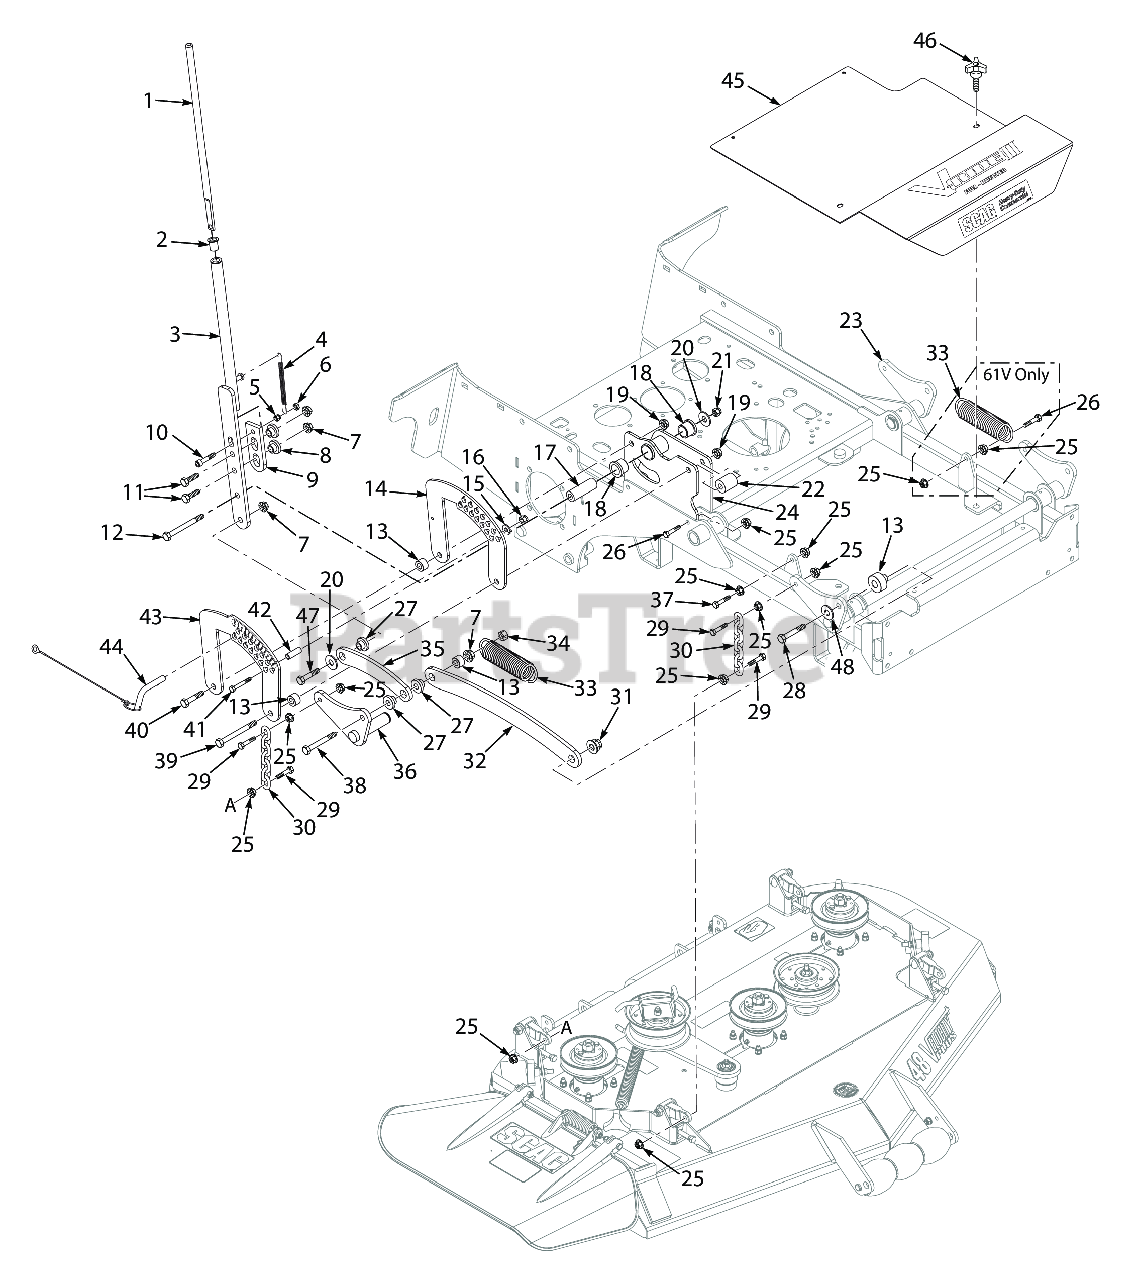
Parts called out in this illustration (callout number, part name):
1	Actuator Rod, Deck Latch
2	Bearing, .625 ID Plastic
3	Handle Weldment, Deck Latch
4	Spring, Deck Latch
5	HEX NUT, ELASTIC STOP LOCK, 3/8-16
6	Bolt, Hex Head 3/8-16 x 1" Ser. Flg.
7	Nut, Hex Serrated Flange 1/2-13
8	Bushing, Deck Latch
9	Deck Latch, Outer
10	Capscrew, Socket Head 3/8-16 x 1-3/4"
11	Bolt, Hex Head 1/2-13 x 1-3/4"
12	Bolt, Hex Head 1/2-13 x 4-1/4"
13	Bushing. Deck Latch
14	Bracket, Deck Height
15	Flatwasher, 3/8" Special (.391 x .938 x .105)
16	HEX NUT, ELASTIC STOP LOCK, 3/8-16
17	Sleeve, Brake Pivot
18	Bearing, Plastic
19	Nut, Hex Serrated Flange 1/2-13
20	Flat Washer, 1/2 (.562 x 1.375 x .109)
21	HEX LOCKNUT, ELASTIC STOP, 1/2-13
22	Spacer, Foot Pedal SZC
23	Arm Weldment, LH
24	Deck Lift Pivot Assy.
25	NUT, 3/8-16 SERRATED FLANGE HEX HEAD
26	Bolt, Hex Head, 3/8-16 x 1 Gr. 5
27	Bushing, Deck Latch
28	Bolt, Hex Hd. 1/2-13 x 2-1/2" (lower)
29	Bolt, Hex Head, 3/8-16 x 1-1/2"
30	Chain
31	Nut, Elastic Stop 1/2-13, (STT-52 & STTII-52)
32	Link, Deck Lift
33	Spring, Deck Lift
34	Locknut, Hex 1/2-13 Center Lock
35	Link, Deck Lift
36	Arm Weldment, RH
37	Bolt, Hex Head 3/8-16 x 1-1/2" Grade 8 Black
38	Bolt, Hex Hd. 1/2-13 x 2-1/2" (lower)
39	Bolt, Hex Head 1/2-13 x 4" (lower)
40	Hex Head Bolt, 1/2-13 x 2"
41	Bolt, Hex Head 3/8-16 x 2-1/4" - 61"
42	Bushing, .502 O.D.
43	Bracket, Deck Height - Outer
44	Pin Assy. w/Lanyard
45	Belt Cover w/Decals
46	Knob, w/stud 3/8-16 x 1-1/4"
47	Bolt, Hex Head 1/2-13 x 1-3/4"
48	Washer, Flat, 1/2-.562 x 1.375 x .109 HD
